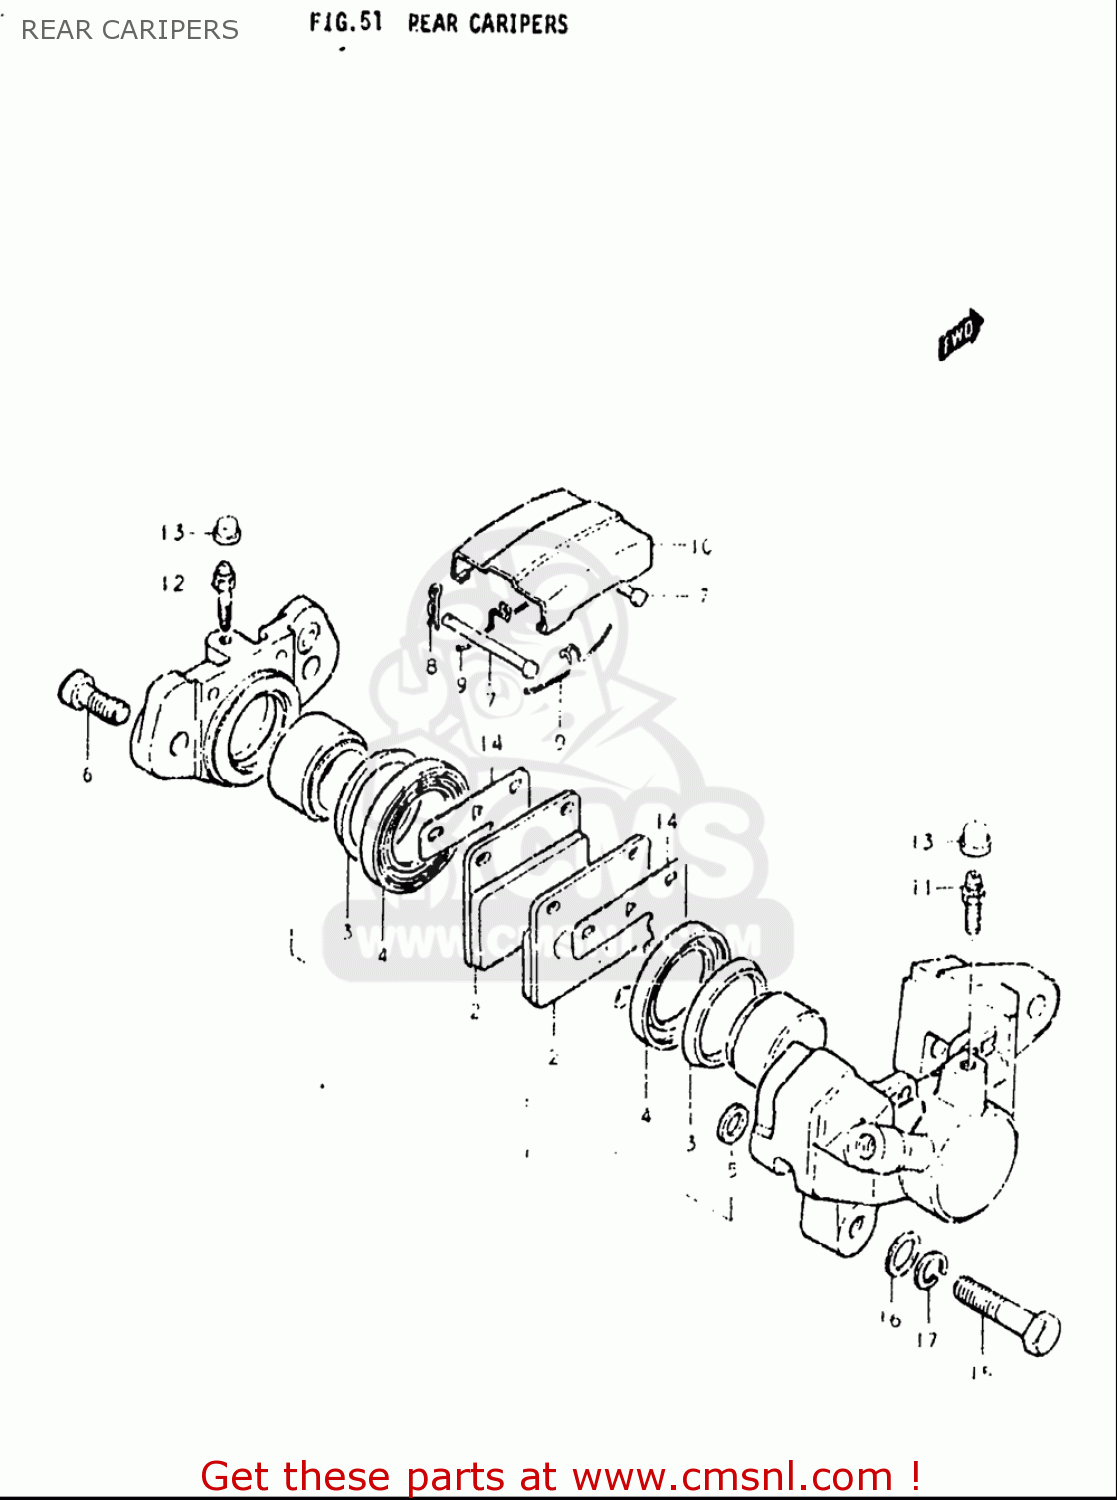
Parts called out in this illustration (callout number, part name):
1	PISTON SET
2	PAD SET (NAS)
3	SEAL,PISTON
4	BOOT,PISTON
5	SEAL,PISTON
6	BOLT,HOUSING
7	PIN,PAD
8	CLIP,PAD PIN
9	SPRING
10	COVER,DUST
11	BLEEDER
12	BREATHER
13	CAP,BLEEDER PLUG
14	SHIM,RR CALIPER
15	BOLT(10X34)
16	WASHER
17	WASHER,LOCK
